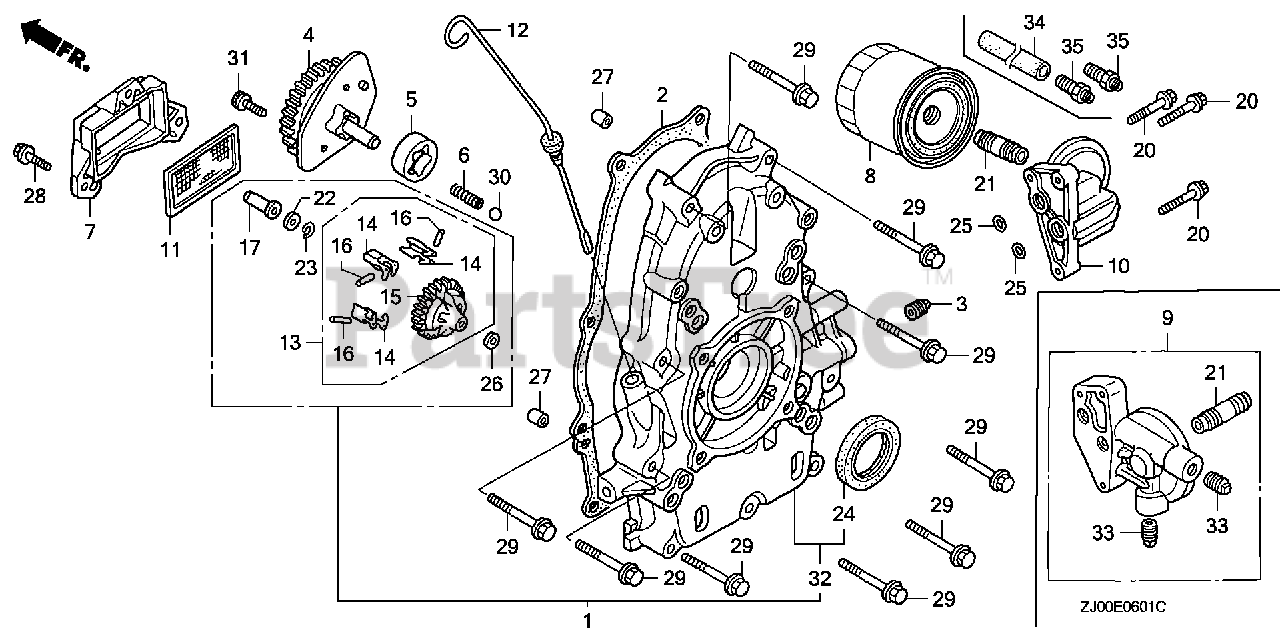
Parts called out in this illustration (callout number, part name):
1	COVER ASSY., CRANKCASE
2	GASKET, CASE COVER
3	BOLT, SEALING
4	COVER ASSY., OIL PUMP (THREE BOLTS)
5	ROTOR, OIL PUMP (OUTER)
6	SPRING, RELIEF VALVE
7	COVER, OIL FILTER
8	FILTER, OIL (FILTECH TOYO ROKI) (SOLD INDIVIDUALLY)
8	FILTER, OIL (TOYO ROKI) (SOLD INDIVIDUALLY)
11	SCREEN, OIL FILTER
12	DIPSTICK, OIL
13	GOVERNOR ASSY.
14	WEIGHT, GOVERNOR
15	HOLDER, GOVERNOR WEIGHT
16	PIN, GOVERNOR WEIGHT
17	SLIDER, GOVERNOR
20	BOLT, FLANGE (6X35) (CT200)
21	HOLDER, OIL FILTER
22	WASHER (6X16)
23	CLIP, GOVERNOR HOLDER
24	OIL SEAL (38X58X9)
25	O-RING (11.8X2.4)
26	WASHER, PLAIN (6MM)
27	PIN, DOWEL (8X14)
28	BOLT, FLANGE (6X20)
29	BOLT, FLANGE (8X50)
30	BALL, STEEL (#12) (3/8)
33	BOLT, SEALING
